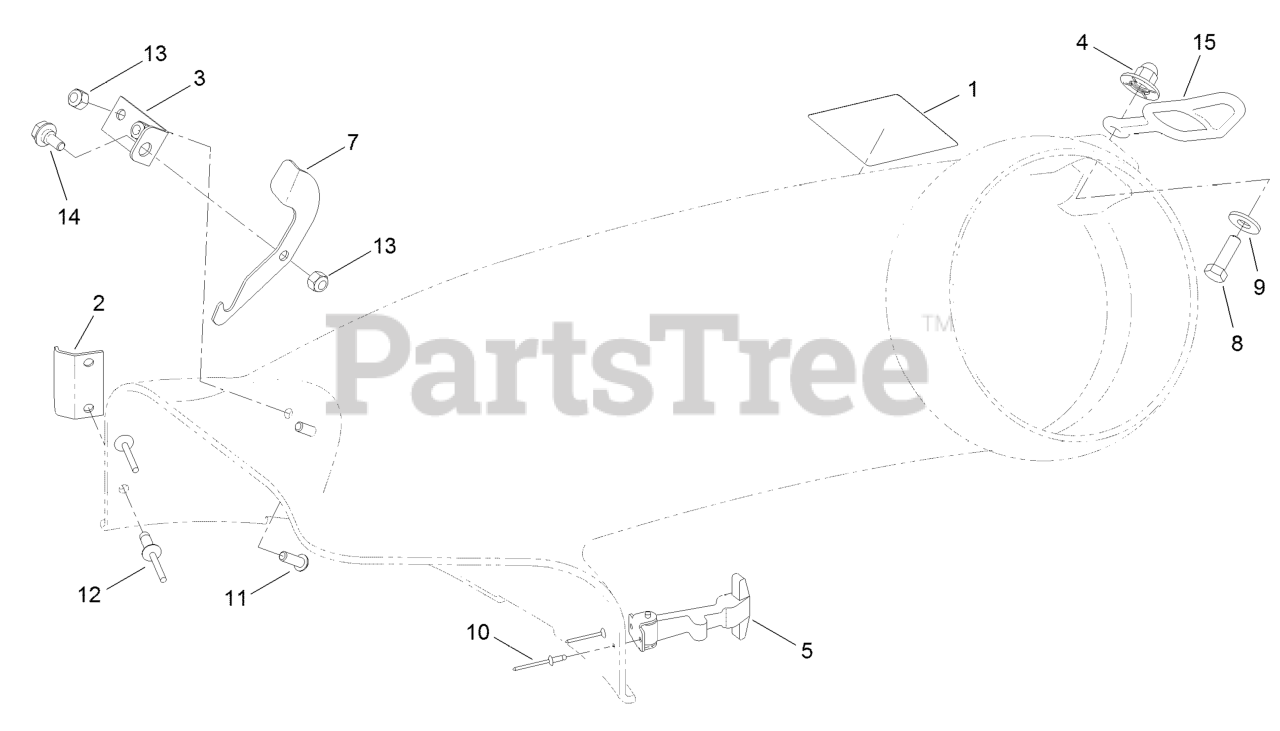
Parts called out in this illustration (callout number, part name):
1	DECAL-DANGER
2	BRACKET-ELBOW
3	PLATE-PIVOT
4	NUT-IMPELLER
5	HANDLE ASM
8	SCREW-HH
9	WASHER-FLAT
10	RIVET-POP
11	SCREW-HSBH
12	RIVET-BLIND
13	NUT-LOCK, NI
15	RETAINER-DUCT
